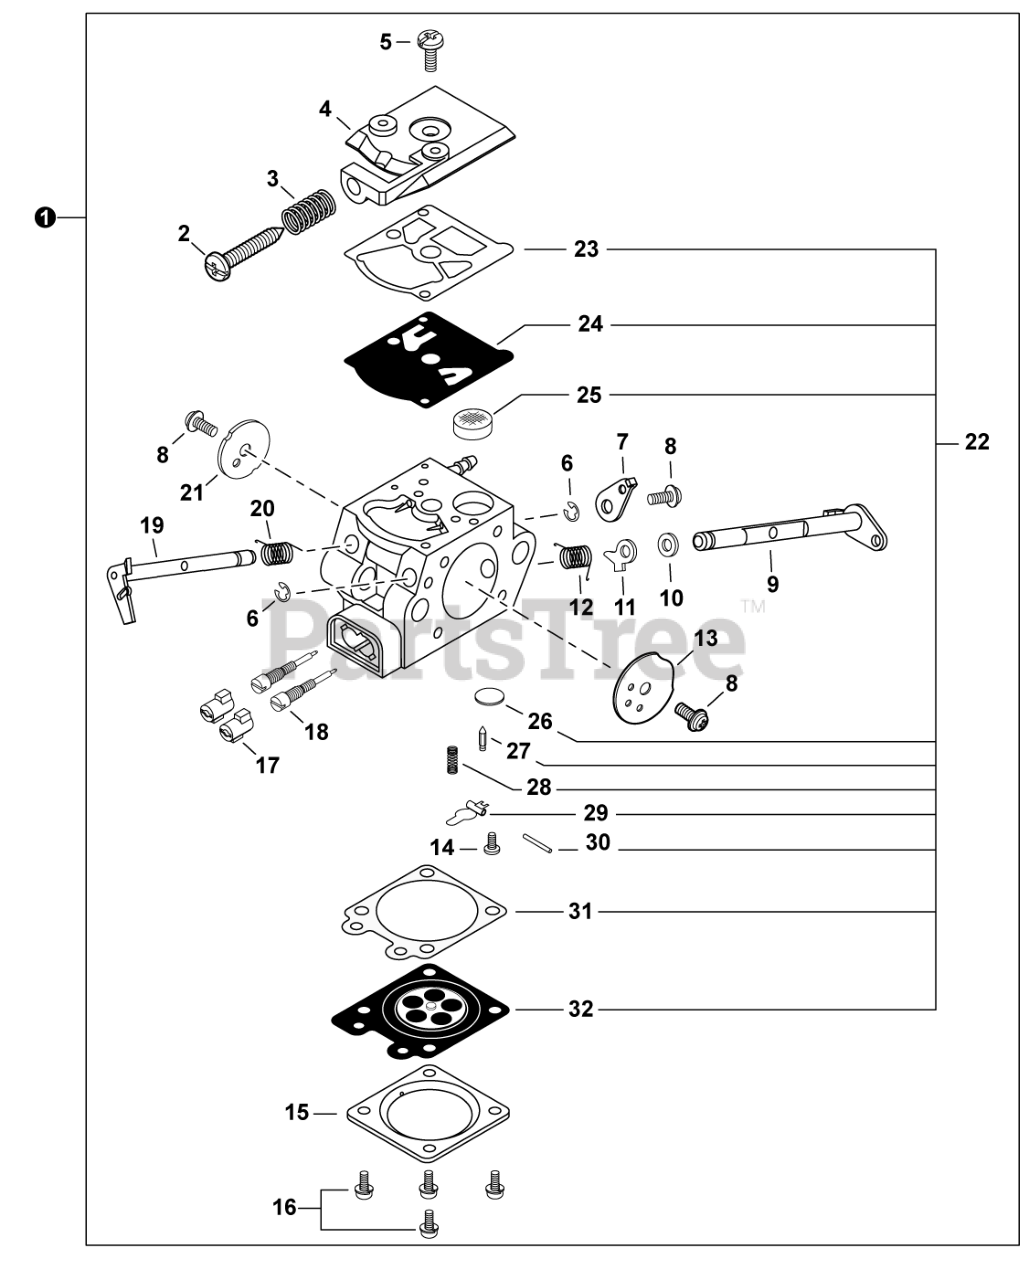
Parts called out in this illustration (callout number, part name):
1	CARBURETOR
2	SCREW, IDLE ADJUST
3	SPRING, IDLE ADJUST
4	COVER, FUEL PUMP
5	SCREW
6	E-RING
7	LEVER, THROTTLE
8	SCREW
9	SHAFT, CHOKE
10	WASHER
11	LEVER, FAST IDLE
12	SPRING
13	VALVE, CHOKE
14	SCREW
15	COVER, METERING DIAPHRAGM
16	SCREW
17	CAP, LIMITER
18	NEEDLE, MIXTURE
19	SHAFT, THROTTLE
20	SPRING, THROTTLE RETURN
21	VALVE, THROTTLE
22	REPAIR KIT, CARBURETOR
23	GASKET, FUEL PUMP
24	DIAPHRAGM, PUMP
25	SCREEN, FUEL INLET
26	PLUG, WELCH
27	VALVE, INLET NEEDLE
28	SPRING, METERING LEVER
29	LEVER, METERING
30	PIN, METERING LEVER
31	GASKET, METERING DIAPHRAGM
32	DIAPHRAGM, METERING
